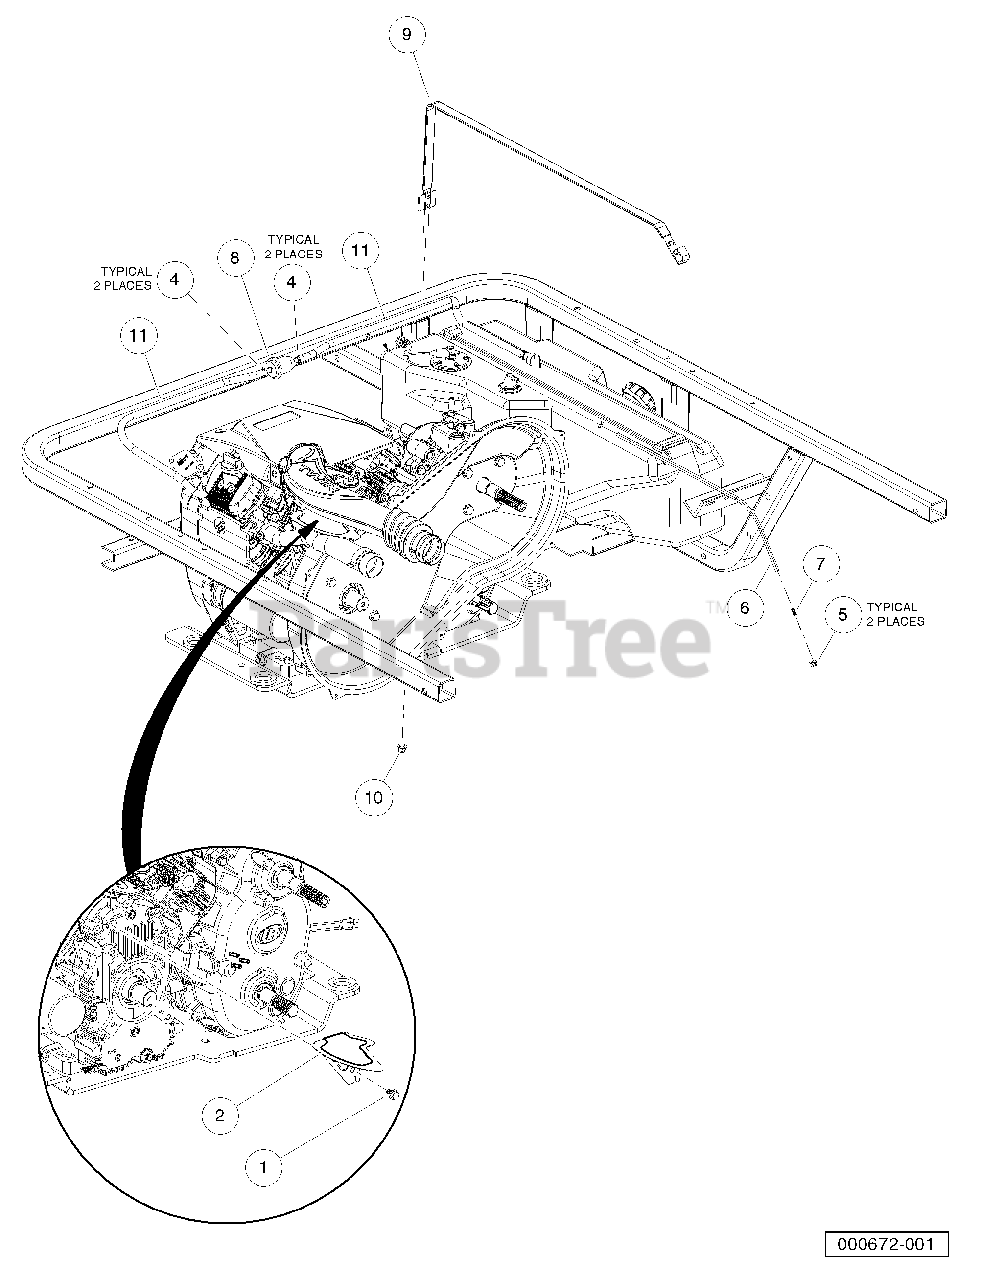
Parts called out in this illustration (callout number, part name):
1	Bolt Flanged Head, M8 X1.25x 16 with Loctite
2	Heat Shield, Header, Gas
4	Clamp, 0.460 Red Hose
5	Clamp, 0.301 ID Hose
6	Hose, Fuel, Vent, 22" Long
8	Filter, Fuel, 30 Micron
9	Strap, Tank, Fuel
10	Lock Nut, Flg M8 X 1.25 Nylon
11	Hose, Tank To Filter, Fh680d
